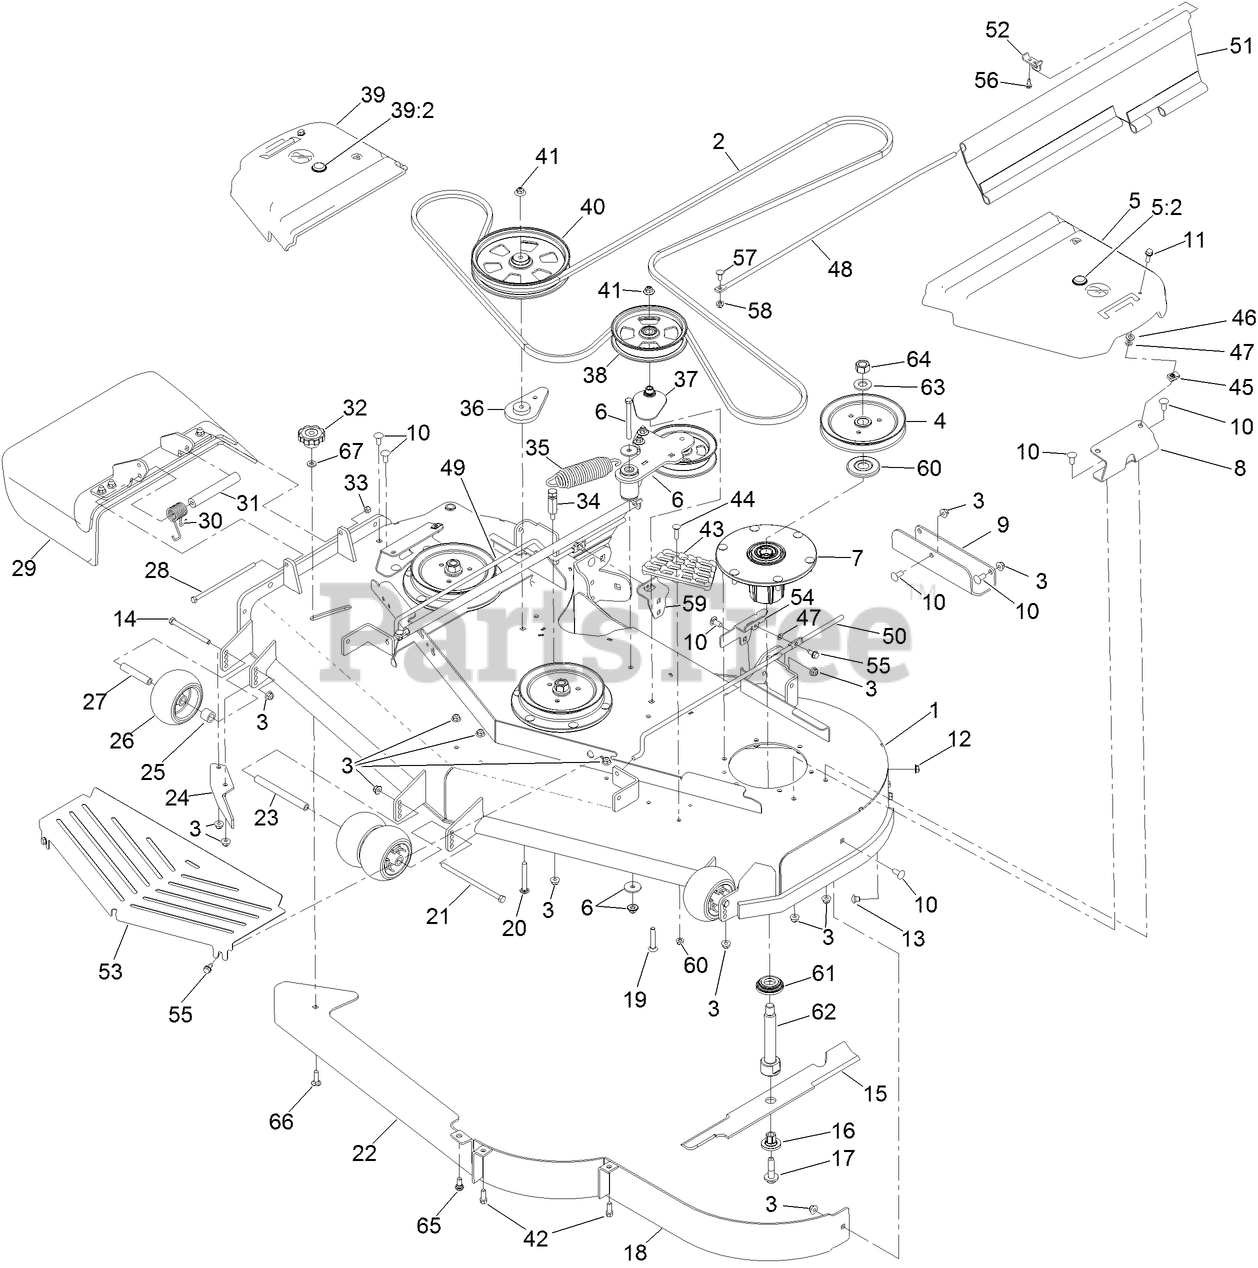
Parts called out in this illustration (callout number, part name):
1	DECK DECAL ASM
2	BELT-V
3	NUT-HF, NI
4	SHEAVE-DRIVE, BLADE
5	LH BELT COVER ASM
5:2	PLUG-PLASTIC
6	IDLER ARM ASM
7	SPINDLE ASM
8	BRACKET-COVER, BELT
9	PLATE-SKID
10	SCREW-CARR
11	SCREW-HHF
12	NUT-HHF, WHIZ
13	SCREW-CARR
14	SCREW-HH
16	BUSHING-HEX
17	SCREW-SEMS
19	BOLT-CARR, SHORT NECK
20	SCREW-CARR
21	SCREW-HH
22	PLATE-BAFFLE
23	SPACER-WHEEL
24	BAFFLE-DISCHARGE
25	TUBE-SPACER
26	ROLLER-SCALP, ANTI
27	TUBE-SPANNER
28	SCREW-HH
29	RUBBER DEFLECTOR ASM
30	SPRING-TORSION
31	SPACER
33	NUT-LOCK, NI
34	ANCHOR-SPRING, TALL
35	SPRING-EXTENSION
36	SPACER-IDLER
37	SPACER-PULLEY
38	PULLEY-IDLER, FLAT
39	RH BELT COVER ASM
39:2	PLUG-PLASTIC
40	PULLEY-IDLER,FLAT
41	NUT-FLANGE, NI
43	STEP-DECK
44	SCREW-CARR
45	NUT-U
46	WASHER-THRUST
47	NUT-PUSH
48	ROD-SUPPORT, UPPER
49	ROD SUPPORT, RH LOWER
50	ROD SUPPORT, LH LOWER
51	GUARD SIDE
52	BRACKET-MOUNTING, UPPER
53	SHIELD-FRONT
54	BRACKET-MOUNTING, REAR (LH)
55	SCREW-HWHTF
56	SCREW-HWH
57	SCREW-CARR
58	NUT-HF, NI
59	BRACKET-MOUNTING, REAR (RH)
60	GUARD-BEARING, TOP
61	GUARD-BOTTOM
62	SHAFT-SPINDLE
63	WASHER
64	NUT-HEX
65	BOLT-SHOULDER
66	BOLT-CARR
67	WASHER-HARDENED
